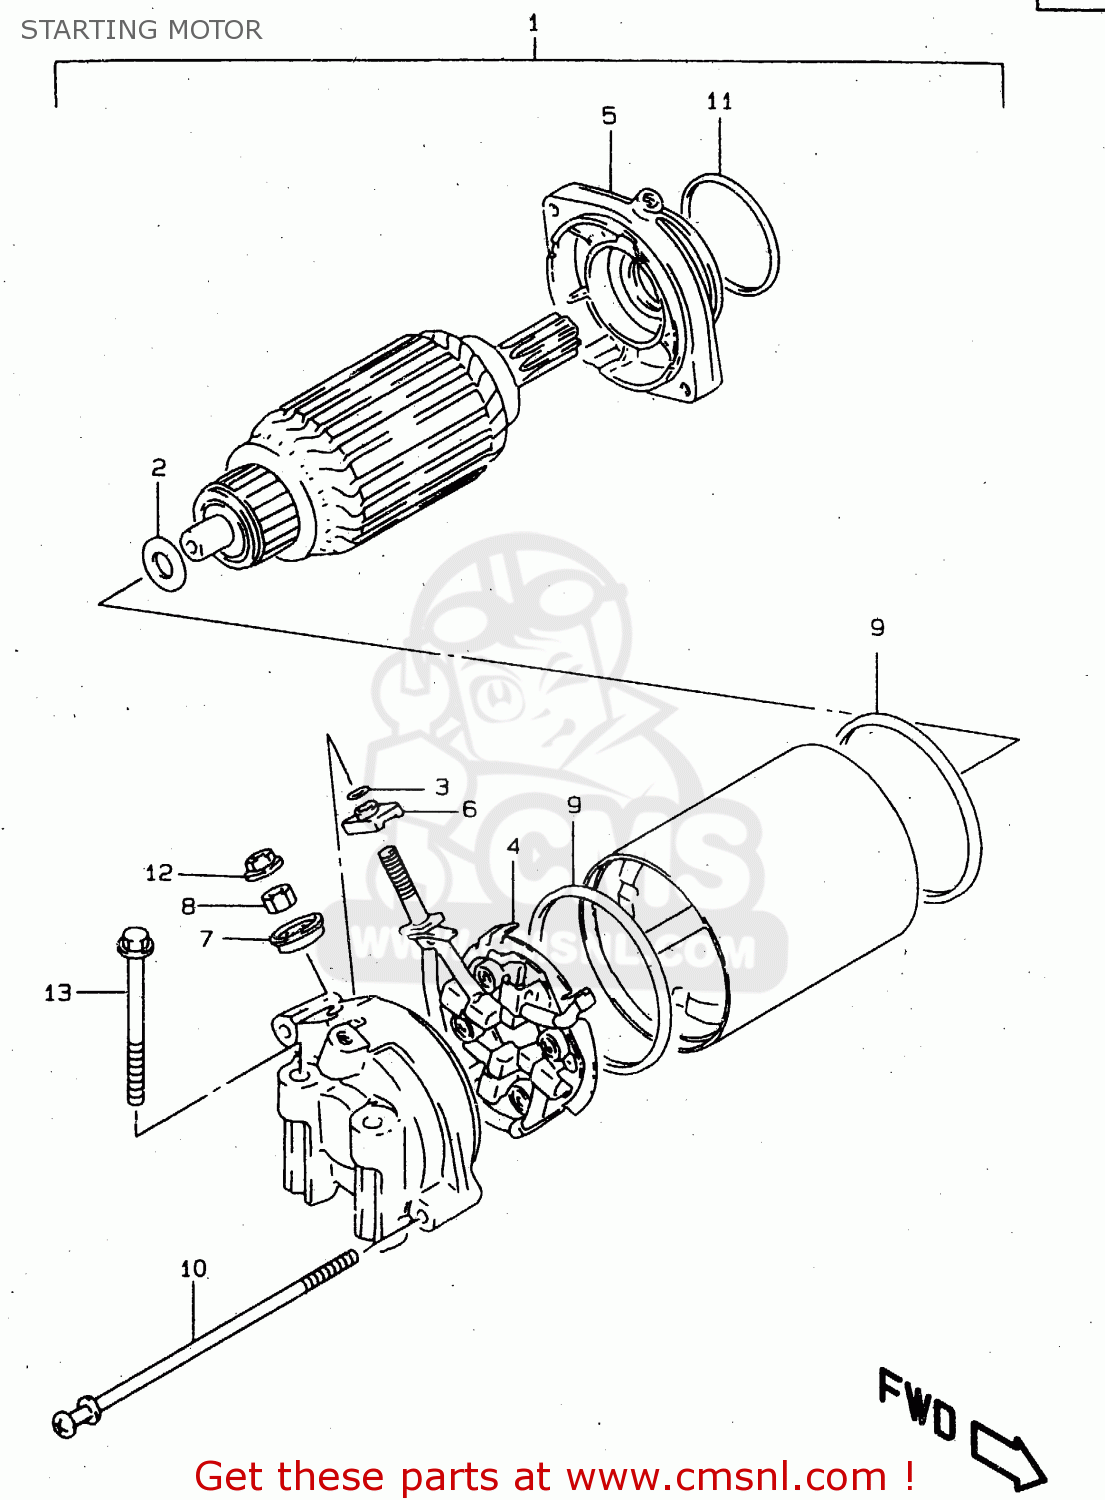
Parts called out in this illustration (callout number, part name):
1	MOTOR ASSY,STARTING
2	SHIM SET,STARTING MOTOR
3	O RING
4	HOLDER SET,BRUSH
5	BRACKET SET
6	BUSHING
7	BUSHING
8	NUT
9	O RING
10	BOLT
11	O RING
12	NUT
13	BOLT
